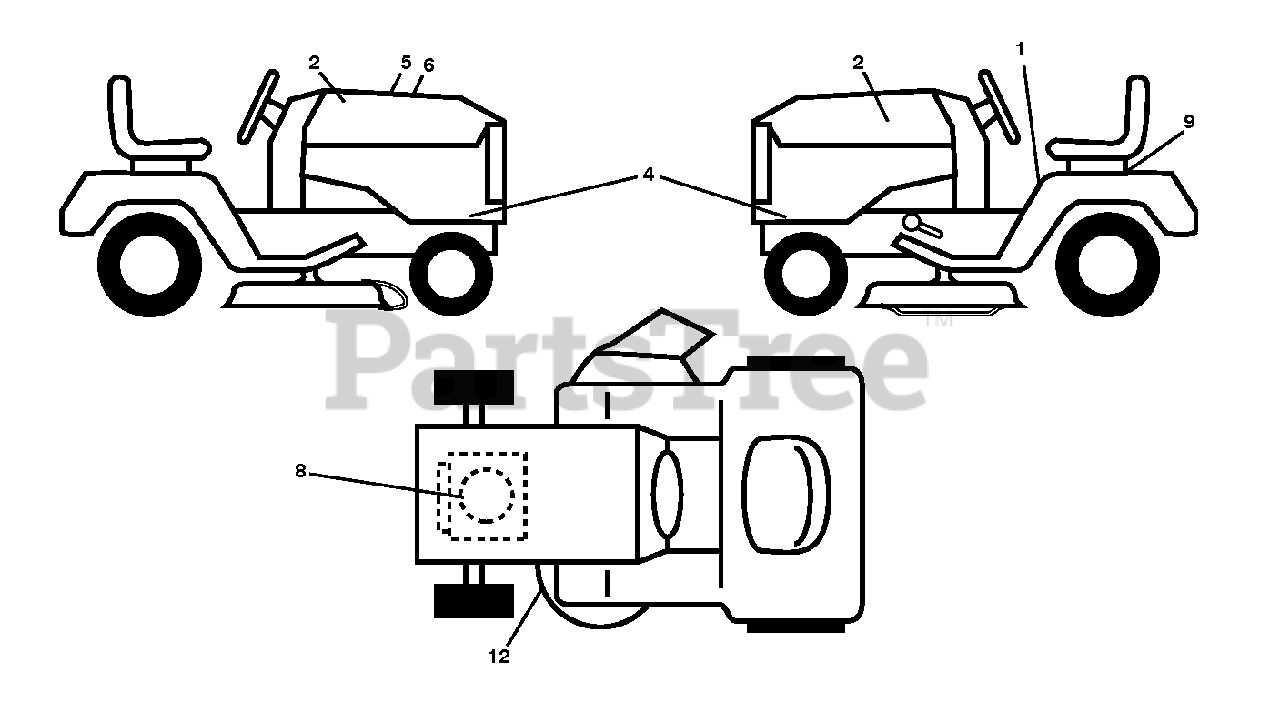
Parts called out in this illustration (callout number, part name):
1	DECAL.FENDER.WARNING
2	RP.DECAL.BADGE.170MM.TEXTLOGO
3	DECAL.WARN.KEEP.HAND.AWAY
4	DECAL.SDPNL.HUSGT2.YTH2042.
5	DECAL.WARNING.CUST.RESP.E85.
6	DECAL RPL.BSM33.INT.TLW.42.K46
8	Decal, Engine BS 20HPXRD
9	DECAL BTRY SYMBOLS
12	DECAL V BELT SCHEMATIC
